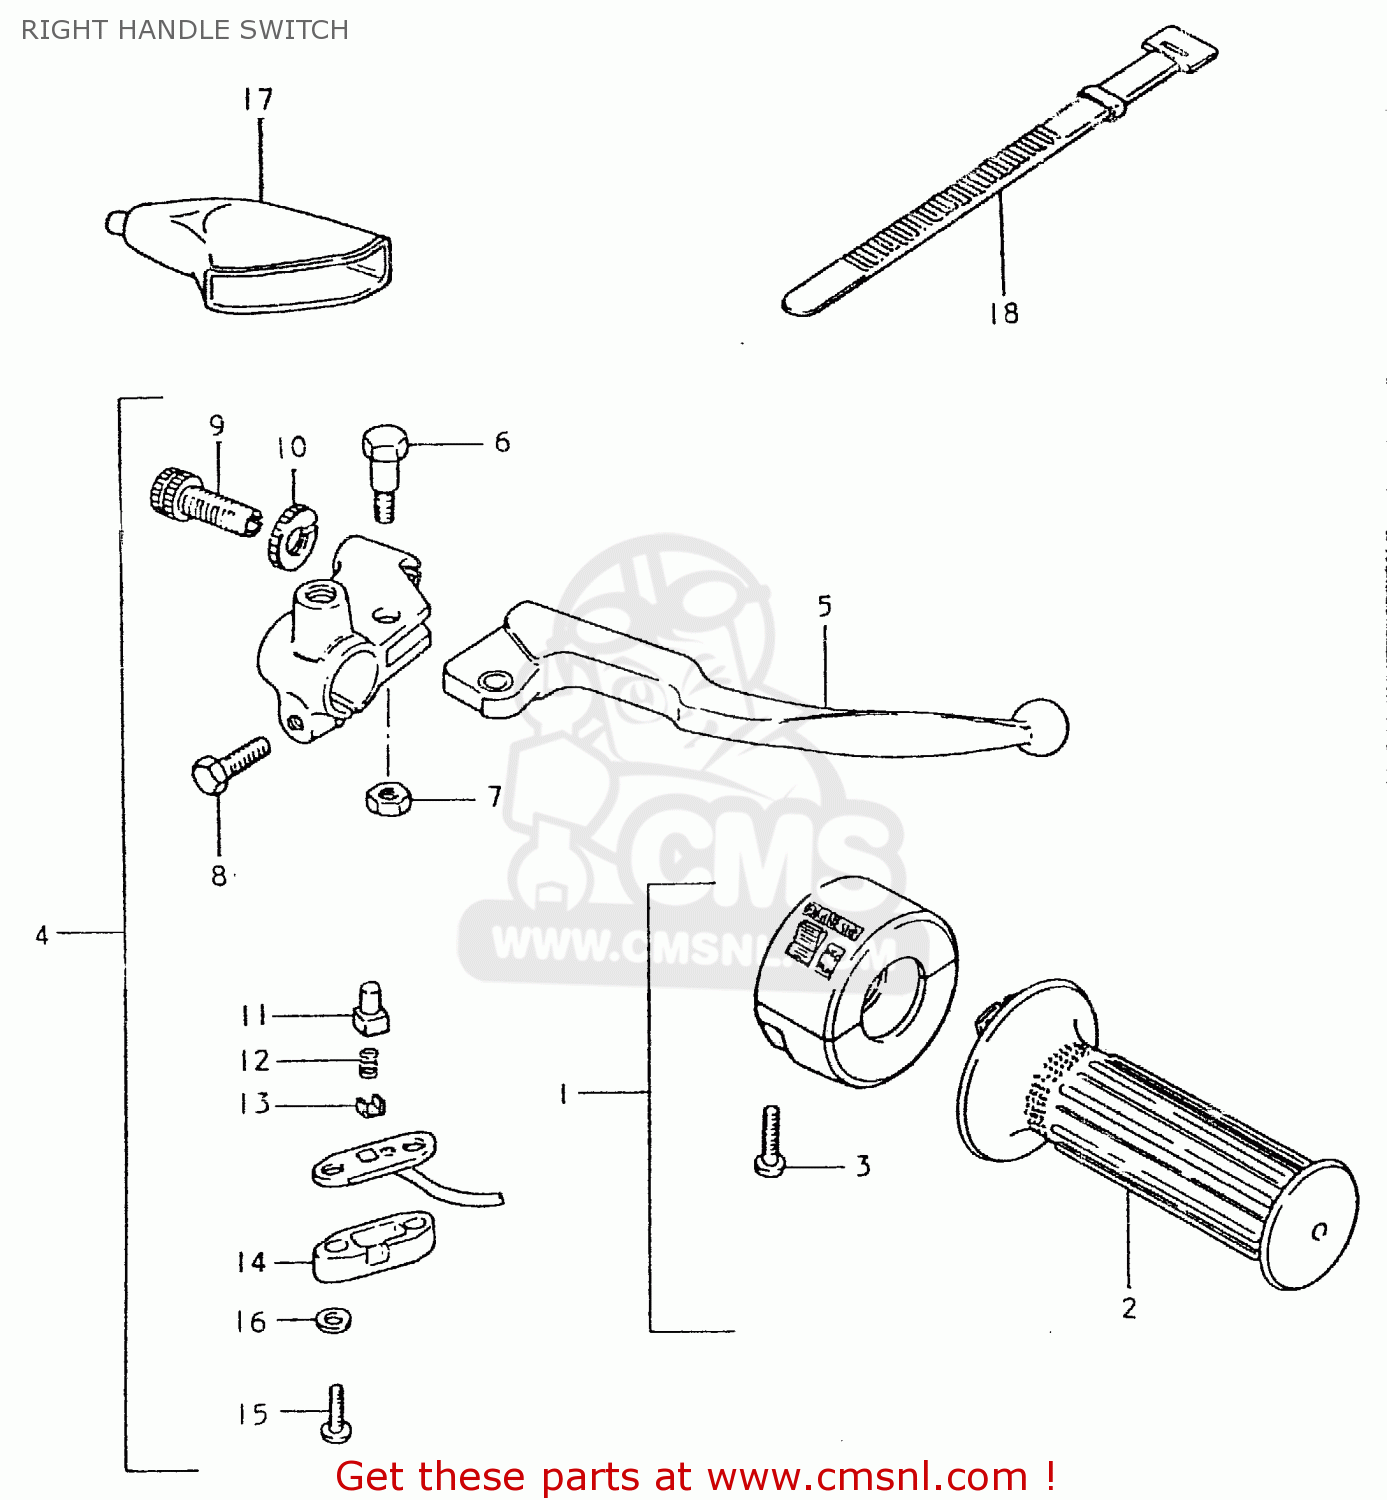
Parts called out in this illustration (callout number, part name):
1	CASE ASSEMBLY,THROTTLE
2	GRIP,THROTTLE
3	SCREW
4	LEVER/SWITCH ASSEMBLY,BRAKE
5	LEVER,BRAKE
6	BOLT,LEVER
7	NUT 6MM
8	BOLT
9	ADJUSTER,CABLE
10	NUT,CABLE ADJUSTER
11	HOLDER
12	SPRING
13	PLATE
14	COVER,FR BK TERMINAL BASE
15	SCREW
16	WASHER
17	COVER,CLUTCH LEVER
18	CLAMP(L:120)
